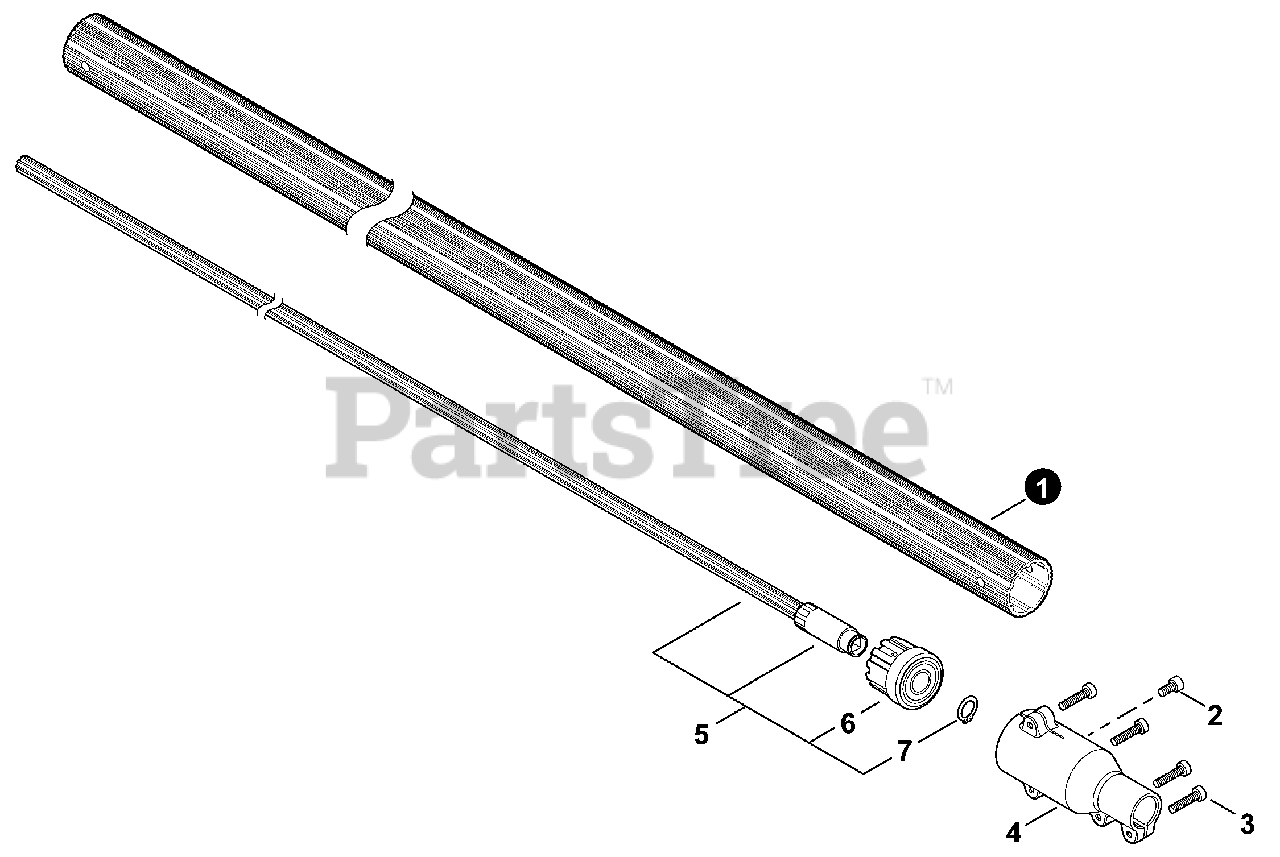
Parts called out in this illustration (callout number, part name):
1	PIPE, MAIN - ORANGE
2	BOLT, TORX 5×16
3	BOLT, TORX 5×20
4	COUPLING, MAIN PIPE
5	DRIVESHAFT ASSY, LOWER
6	HOLDER ASSY, BEARING
7	RING, RETAINING
